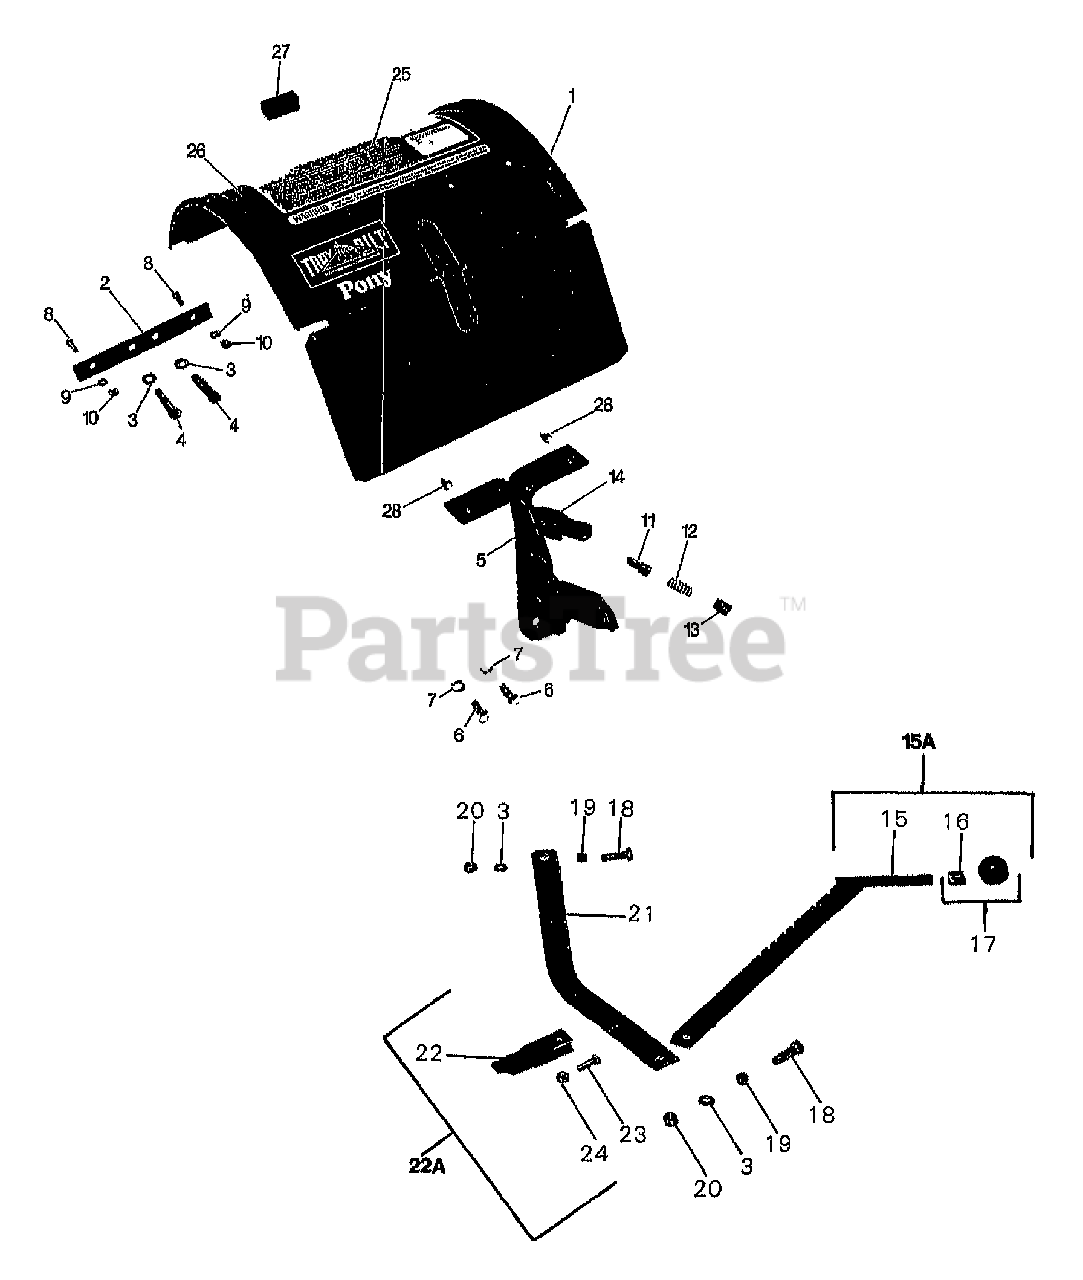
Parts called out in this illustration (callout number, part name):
1	HOOD W/DECAL (#20662 & #20401)
2	PLATE-HOOD MTG (REPLACES SHORTER VERSION USED ON P14465 & EARLIER)
3	WASHER-LK .375 @ DEPL
4	BOLT-HH 3/8-16 X 2 ZP
5	KIT-REAR HOOD BRKT (INCL. ROLL PIN #9308)
6	SCR-HHC 5/16-18X.75 GR 5 ZP (BRACKET TO REAR BEARING CAP)
7	WASHER-LK .312 ZP
8	SCR-RH 1/4-20 X .75 ZP (HOOD TO PLATE)
9	WASHER-LK .25 ZP
10	NUT-HEX 1/4-20 ZP
11	PLUNGER
12	SPRING .406 X 1.25
13	PLUG-PIPE 1/4 NPT
14	PIN-ROLL .25 X 1
15	BAR (NOT AVAIL.SEP., SEE #15A)
15A	DEPTH REGULATOR W/KNOB (INCL. 15 & 17)
16	RING-TOLERANCE .5325 ID
17	KNOB-CONTROL (INCL. #16)
18	SCR-HH 3/8-16X1.25
19	BUSHING-.5X.375X.3 (REPLACES 1113)
20	NUT-HEX 3/8-16 ZP
21	BAR-DRAG
22	SOD POINT (NOT AVAIL. SEP., SEE #22A)
22A	SOD POINT (INCL. #9811, #9701, AND SOD POINT) (NOT AVAIL. SEP.)
23	SCR-HH 1/4-20X.75 G5 ZP
24	NUT-LK 1/4-20
25	DECAL-OPER INST
26	DECAL-HOOD LOGO PONY OPC
27	SPACER 1 SQ X 2.25 (BETWEEN HANDLEBAR HEIGHT ADJUSTMENT BRACKET AND HOOD)
28	SCR-HWH 1/4-20 X .5 STH (HOOD TO HOOD/DEPTH REGULATOR BRACKET)
